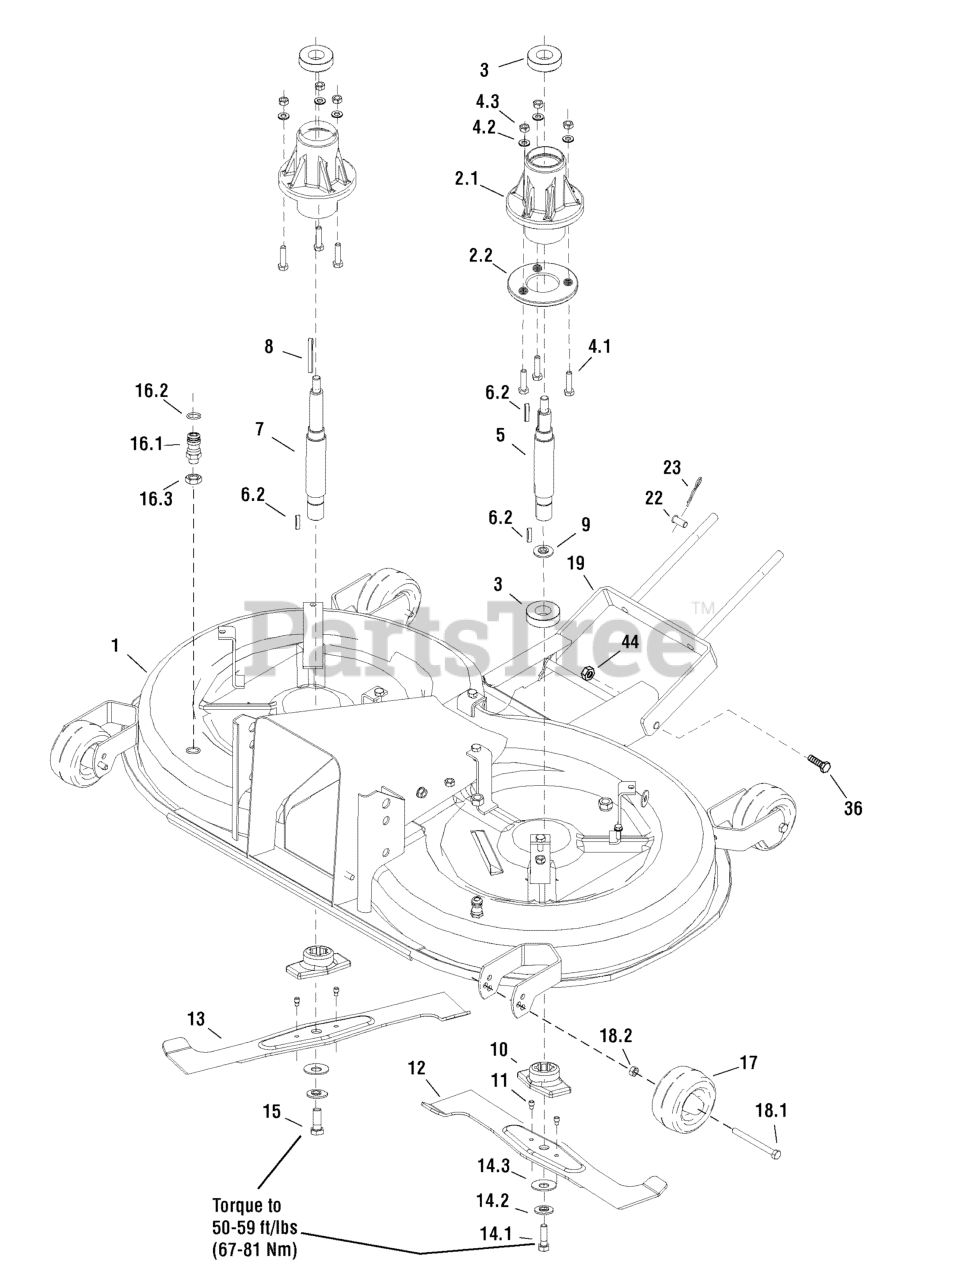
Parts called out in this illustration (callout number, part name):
1	MOWER DECK, Complete
2.2	REINFORCEMENT
3	BEARING, 6205 2 RS C 66IB
4.1	SCREW, M8 x 35
4.2	WASHER, 8.4
4.3	NUT, M8
4.3	NUT, Flange Lock, M8
6.2	TONGUE, 6 H 9 x 6 x 28
8	TONGUE, 6 H 9 x 6 x 63
9	RING, Safety 25
11	SHEAR STUD, 0-9311-736
12	BLADE, Right Rotary
13	BLADE, Left Rotary
14.1	SCREW, M10, 0-9011-287
14.2	WASHER, 0-9220-749
14.3	WASHER, BN 806-40 x 16.3 x 2 x 3.1
15	SCREW, 0-9011-283 M10, Left Thread
16.1	QUICK FASTENER, 0-9026-246
16.2	RING, 13 x 2 NBR
16.3	NUT, M12
17	CUTTING WHEEL, Right ETOP 100-8.2
18.1	SCREW, M8 x 90
18.2	NUT, Flange Lock, M8
19	HINGE, Front
22	MOWING STUD, 1-9310-290
23	PIN, Flexible 0-9245-999
36	BOLT, M12 x 25
44	NUT, M12
